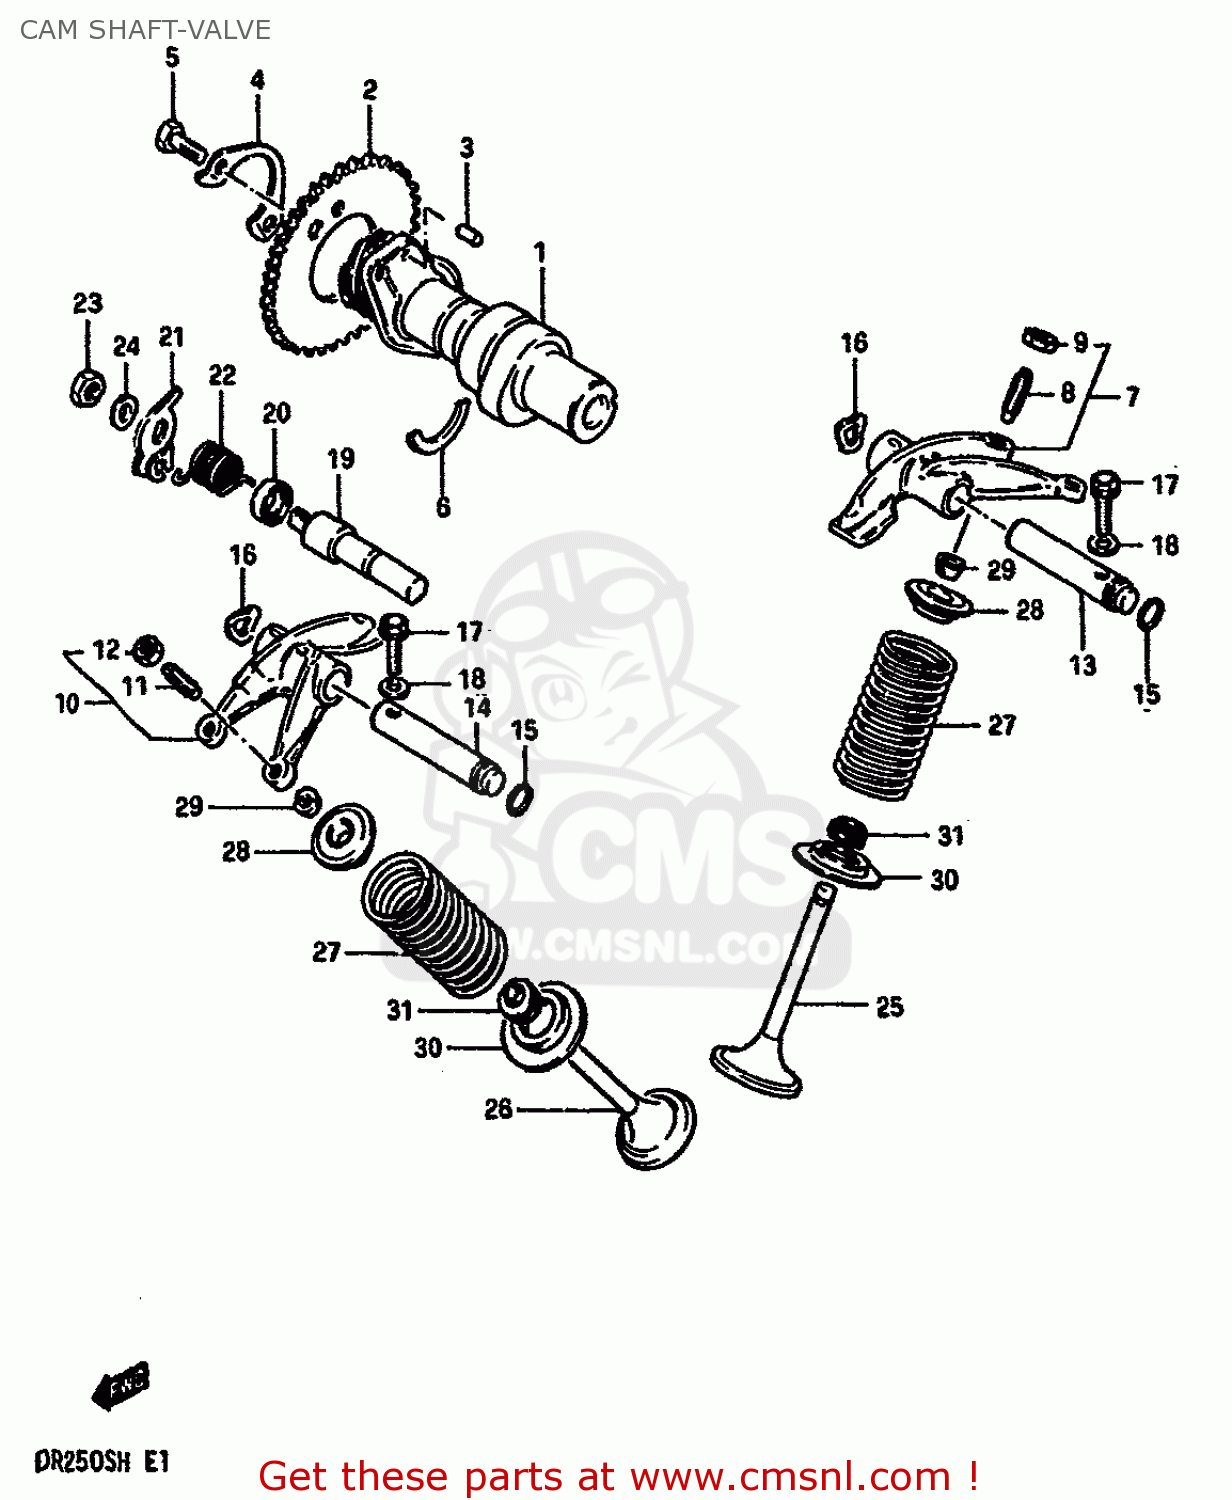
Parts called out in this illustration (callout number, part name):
1	CAMSHAFT
2	SPROCKET,CAMSHAFT(NT:42)
3	PIN
4	WASHER,CAM CHAIN SPROCKET
5	BOLT(6X12.5)
6	C RING
7	ARM,VALVE ROCKER INTAKE
8	SCREW,TAPPET ADJUSTING
9	NUT,ADJUSTING
10	ARM,VALVE ROCKER EXHAUST
11	SCREW,TAPPET ADJUSTING
12	NUT,ADJUSTING
13	SHAFT,VLV ROCKER ARM IN(L:91.5
14	SHAFT,VLV ROCKER ARM EXH(L:76)
15	O RING(D:1.9,ID:8.6)
16	WASHER
17	BOLT 6X30
18	GASKET(5.8X13X1.2) (NAS)
19	SHAFT,DECOMP LH
20	OIL SEAL
21	LEVER,DECOMP SHAFT
22	SPRING
23	NUT 8MM
24	WASHER
25	VALVE,INTAKE
26	VALVE,EXHAUST
27	SPRING,VALVE
28	RETAINER,VALVE SPRING
29	COTTER VALVE
30	SEAT,VALVE SPRING
31	OIL SEAL
